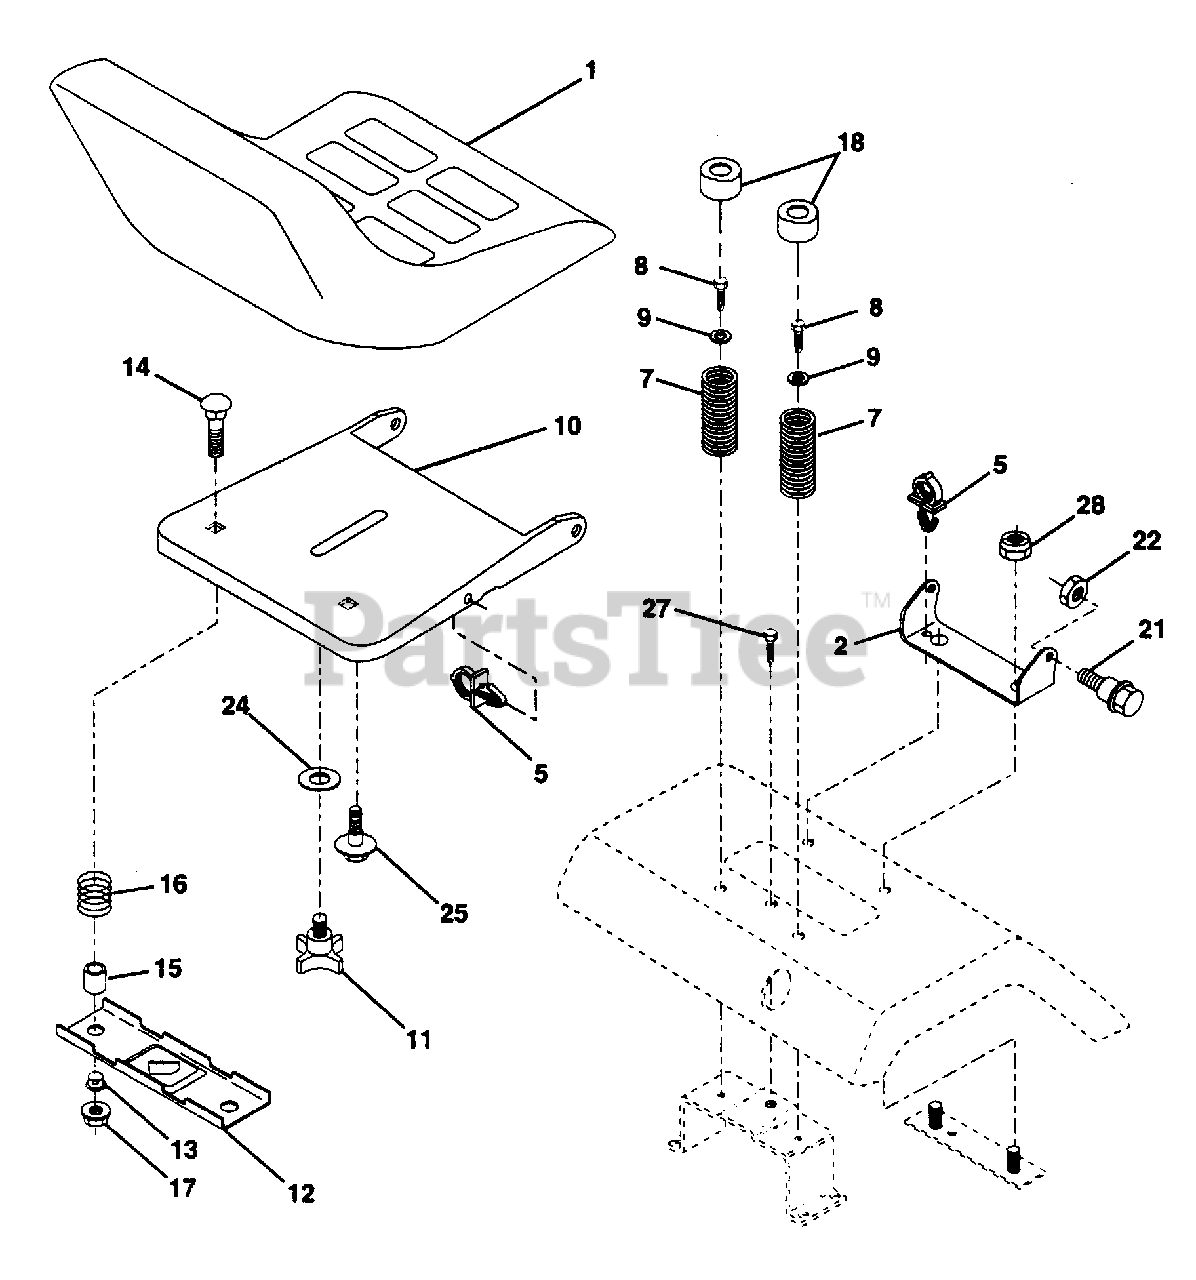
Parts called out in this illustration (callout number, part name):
1	Seat V-560 Blk/blk Std (AYP part number)
2	Bracket Pivot Seat 8 720 (AYP part number)
5	Clip Push-in Hinged (AYP part number)
7	Spring Seat Cprsn 2 250 Blk Zi (AYP part number)
8	Screw Hwsh Thdrol 5/16-18 x 1/2 (AYP part number)
9	Washer 13/32 X 1 X 14 Ga (AYP part number)
10	Pan Seat (AYP part number)
11	Knob Seat 1/2-13unc Blk (AYP part number)
12	Bracket Mounting Switch (AYP part number)
13	Bushing Snap Blk Nyl 50 Id (AYP part number)
14	Bolt Rdhd Sht Nk 1/4-20x1-3/8
15	Spacer Split 28x 88 Yel Zinc (AYP part number)
16	Spring Cprsn 1 310 Blk Pnt (AYP part number)
17	Nut Lock 1/4 Lge Flg Gr 5 Zinc (AYP part number)
18	Cap Spring Seat (AYP part number)
21	Bolt Shoulder 5/16-18 Unc Blkz (AYP part number)
22	Nut Crown Lock 5/16-18
24	Washer 17/32 X 1-3/16 X 12 Ga (AYP part number)
25	Bolt Shoulder 5/16-18 X 62 (AYP part number)
27	Screw Thdrol 3/8 - 16 x 1/2 Ty-TT (AYP part number)
28	Nut Crownlock 3/8-16 Unc
